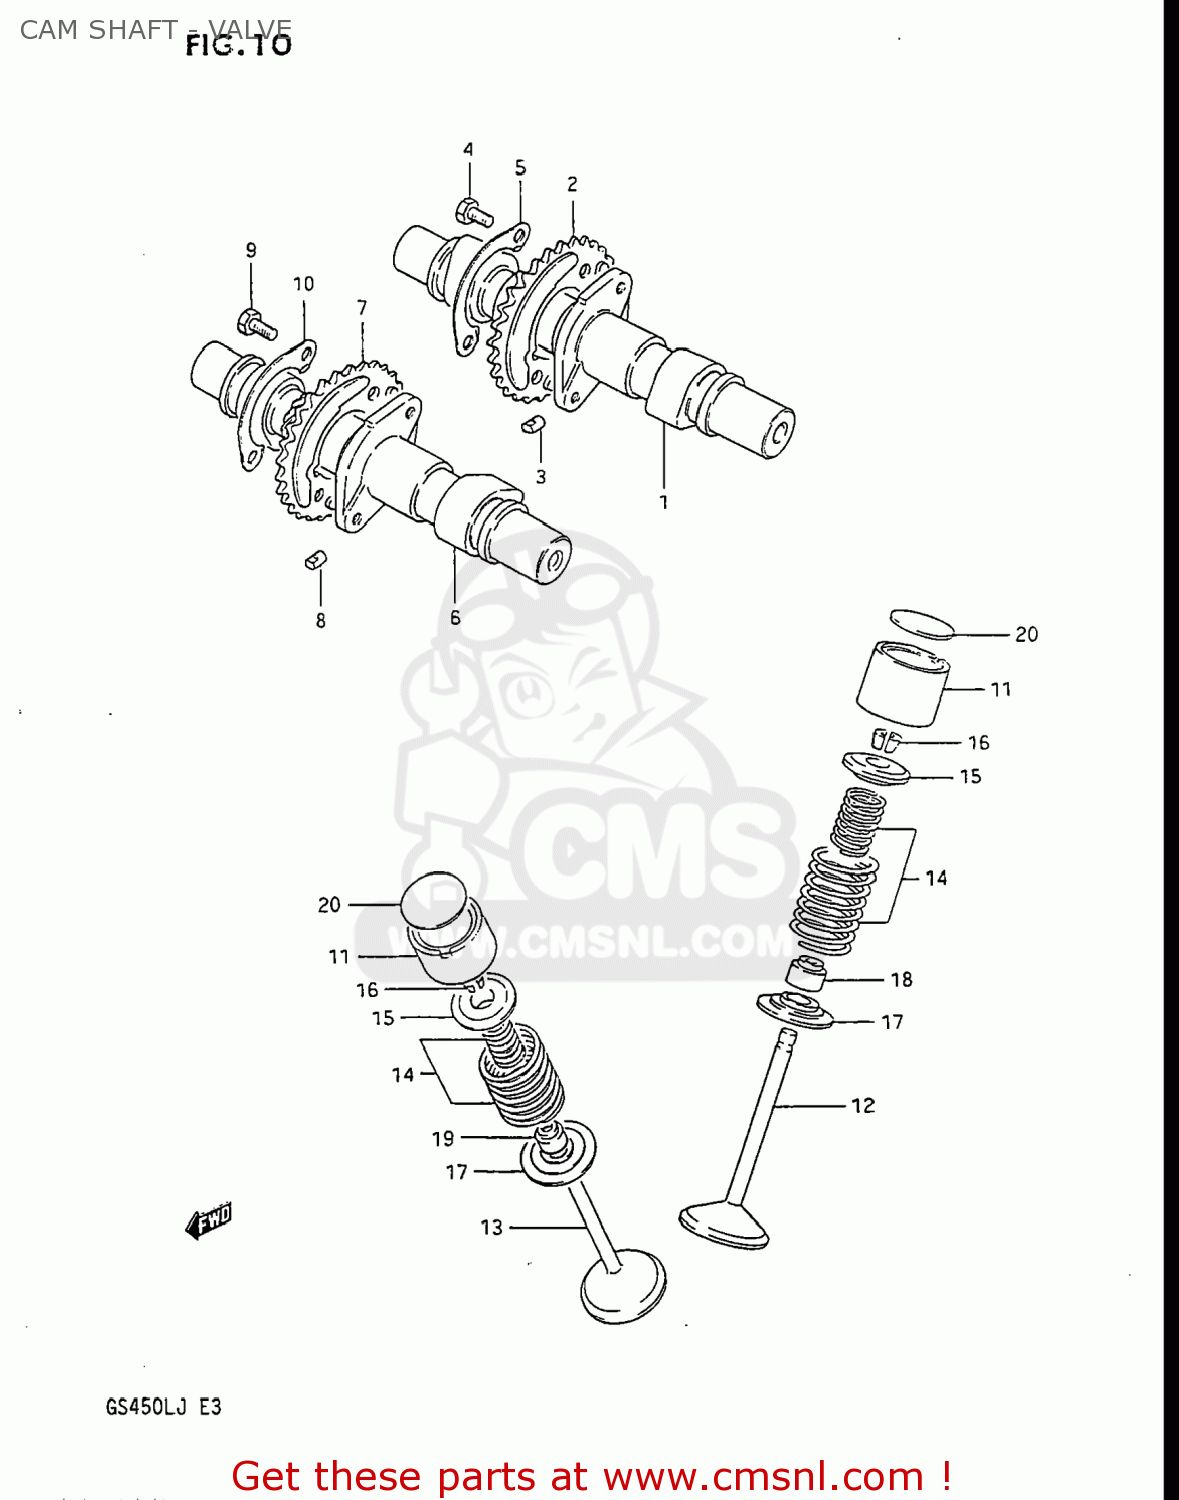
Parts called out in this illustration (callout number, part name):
1	CAMSHAFT,INTAKE
2	SPROCKET,CAMSHAFT
3	PIN,SPROCKET
4	BOLT(6X12.5)
5	WASHER,CAM CHAIN SPROCKET
6	CAMSHAFT,EXHAUST
7	SPROCKET,EXHAUST CAM(NT:30)
8	PIN,SPROCKET
9	BOLT(6X12.5)
10	WASHER,CAM CHAIN SPROCKET
11	TAPPET,INTAKE
12	VALVE,INTAKE
13	VALVE,EXHAUST
14	SPRING SET,VALVE
15	RETAINER,VALVE SPRING
16	COTTER VALVE
17	SEAT,VALVE SPRING
18	SEAL,OIL(7X14.4X9)
19	SEAL,OIL(7X14.5X10.5)
20	SHIM,TAPPET(T:2.15)
21	SHIM SET,TAPPET
22	CASE
